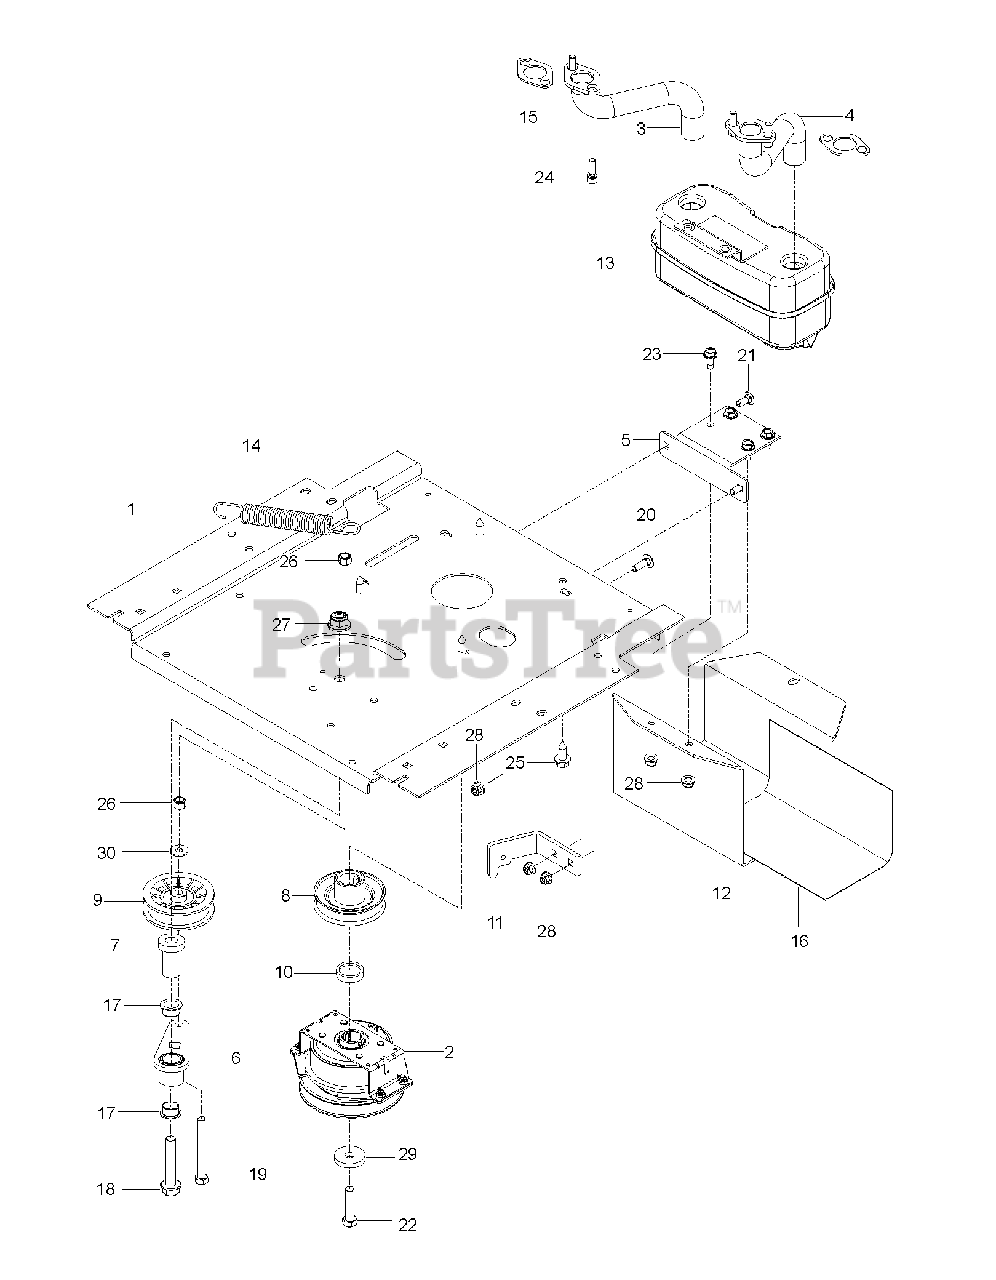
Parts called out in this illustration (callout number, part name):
1	PLATE.ENGINE.PNT.23"FRAME.EDIP
2	CLUTCH.OGURA.5.0PD.GT1.5A-EH07
3	EXHAUST.TUBE.RH.B&S.TWIN.INTEK
4	EXHAUST.TUBE.LH.BS/TWIN
5	BRACKET MUFFLER MS431BLK
6	ARM IDLER
7	SPINDLE.IDLER
8	PULLEY.ENGINE
9	PULLEY, IDLER RAKE & ZTR
10	SPACER.SPACER.625 W/OGURA.LCC
11	CLUTCH.STOP.OGURA LCC.BLACK
12	GUARD.MUFFLER.WO.TOW.HITCHX431
13	MUFFLER ASM TWIN
14	SPRING, DECK DRIVE
15	GASKET.MUFFLER
16	HEAT SHIELD
17	BEARING.FLANGED.PLASTIC.3/4ID
18	BOLT.FLANGE.1/2-13 X 2.75.GRD5
19	HCS 3/8-16X3-1/2 TAPBLT GR5 ZD
21	BOLT 5/16-18 X3/4 ZN/YEL GR 5
22	CLUTCH BOLT7/16-20X2.5 GR524HR
23	SCREW
24	SCREW.SOCKET.HEAD.5/16-18
25	SCREW 3/8-16X1
26	NUT 3/8-16 NYLOC
27	NUT, 1/2-13 HEX FLG NYLOC ZD
28	5/16-18 NYLOC FLANGE NUT
30	WASHER
